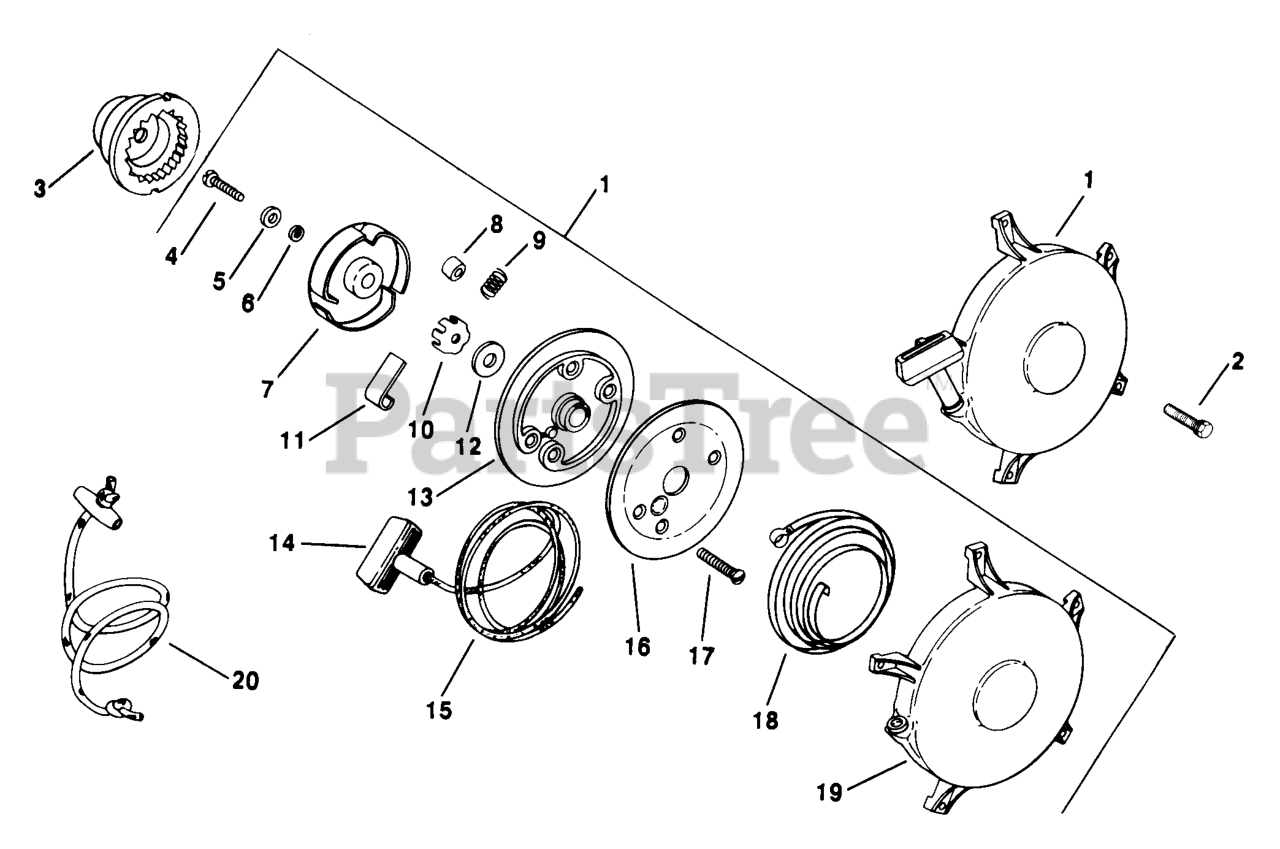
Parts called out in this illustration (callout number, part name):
1	STARTER
3	CUP, DRIVE - DISCONTINUED
5	WASHER - DISCONTINUED
7	RETAINER
9	SPRING - DISCONTINUED
9	SPRING
11	DOGS - DISCONTINUED
14	HANDLE - USE 25 166 01
19	HOUSING - DISCONTINUED
